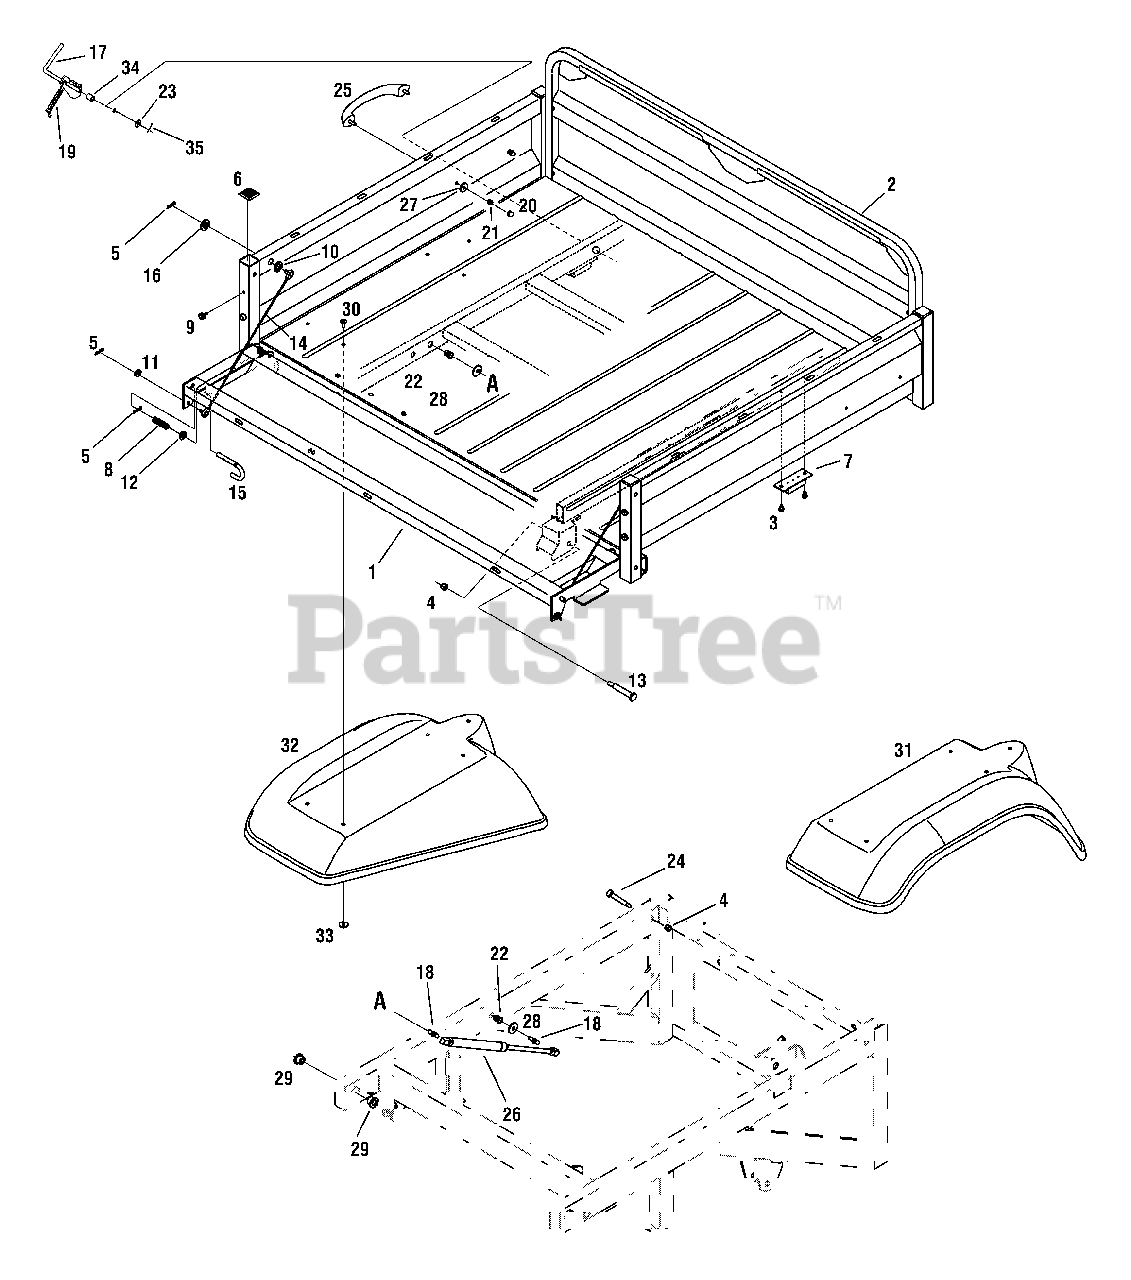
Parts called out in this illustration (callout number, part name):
1	Tailgate Assembly
2	Bed Assembly
3	Screw, Self-tapping, 1/4-20 x 0.500
4	Nut, Nylon Hex Lock, 3/8-16
5	Cotter Pin, .072 Dia x 1.13
7	Bumper, Extension Suspension
8	Compression Spring, .406 x .531 x
9	Bumper, .62 x .3
10	Washer, Flat, .64 ID x 1.0 x .12
11	Washer, Flat, .344 x .750 x .120
12	Washer, Flat, .407 x .812 x .135
13	Screw, Shoulder, 1/2 x 2.5
14	Cable, LIft 16.16 LG
15	Handle, Deck Release
16	Spacer, Shoulder .625 x .324 Dia
17	Latch Assembly
18	Stud, Ball 5/16-18
19	Extension Spring
20	Nut, Acorn 1/4-20 w/o Lock
21	Nut, Hex Lock, 1/4-20
22	Nut, Insert 5/16-18
23	Flat Washer,.406 x.875 x.059
24	Shoulder Bolt, 3/8-16 x .5OD x 2.0
25	Handle, Bag w/Screw
26	Spring, Gas .91 Stroke
27	Washer, Flat .265 x .938 x .120
28	Washer, Flat .344 x 1.125 x .120
29	Flange Bearing, .51
30	Pop Rivet, .188
31	Fender, Rear RH, Camo
32	Fender, Rear LH, Camo
33	Flat Washer, .194 x .62 x .063
34	Spacer,.385 x.625 x.700
35	Cotter Pin
